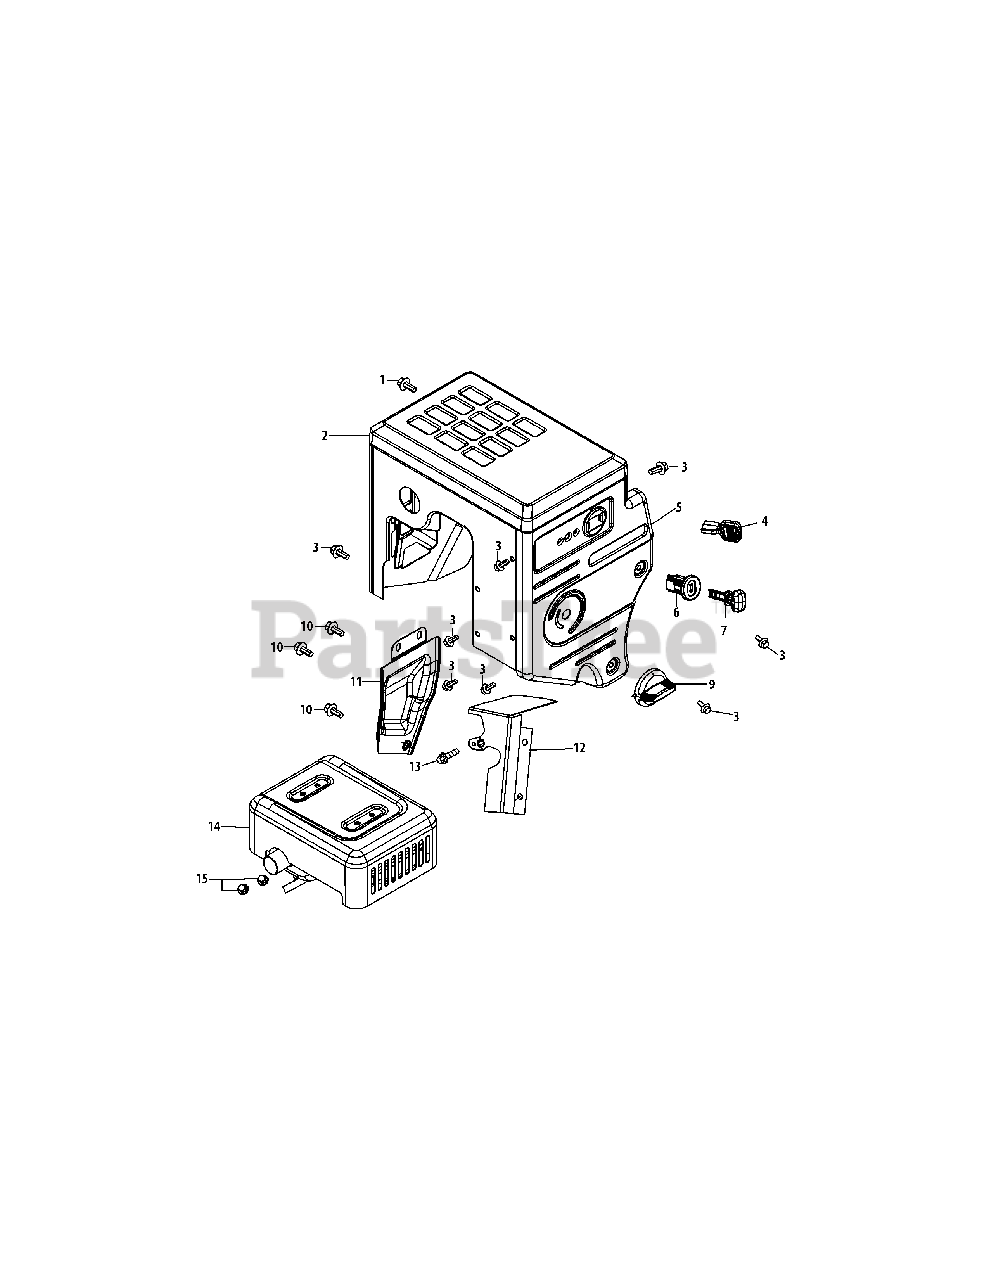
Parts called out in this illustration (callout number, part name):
1	Bolt,M6×16
2	Muffler Shield
3	Bolt M6×12
4	Throttle Control Knob
5	Control Panel
6	Key Switch Base
7	Key
9	Choke Knob
10	Bolt M6×20
11	Exhaust Pipe Shield
12	Carb Isolator Bracket
13	Bolt M6×16
14	Muffler Assembly
15	Nut M8
